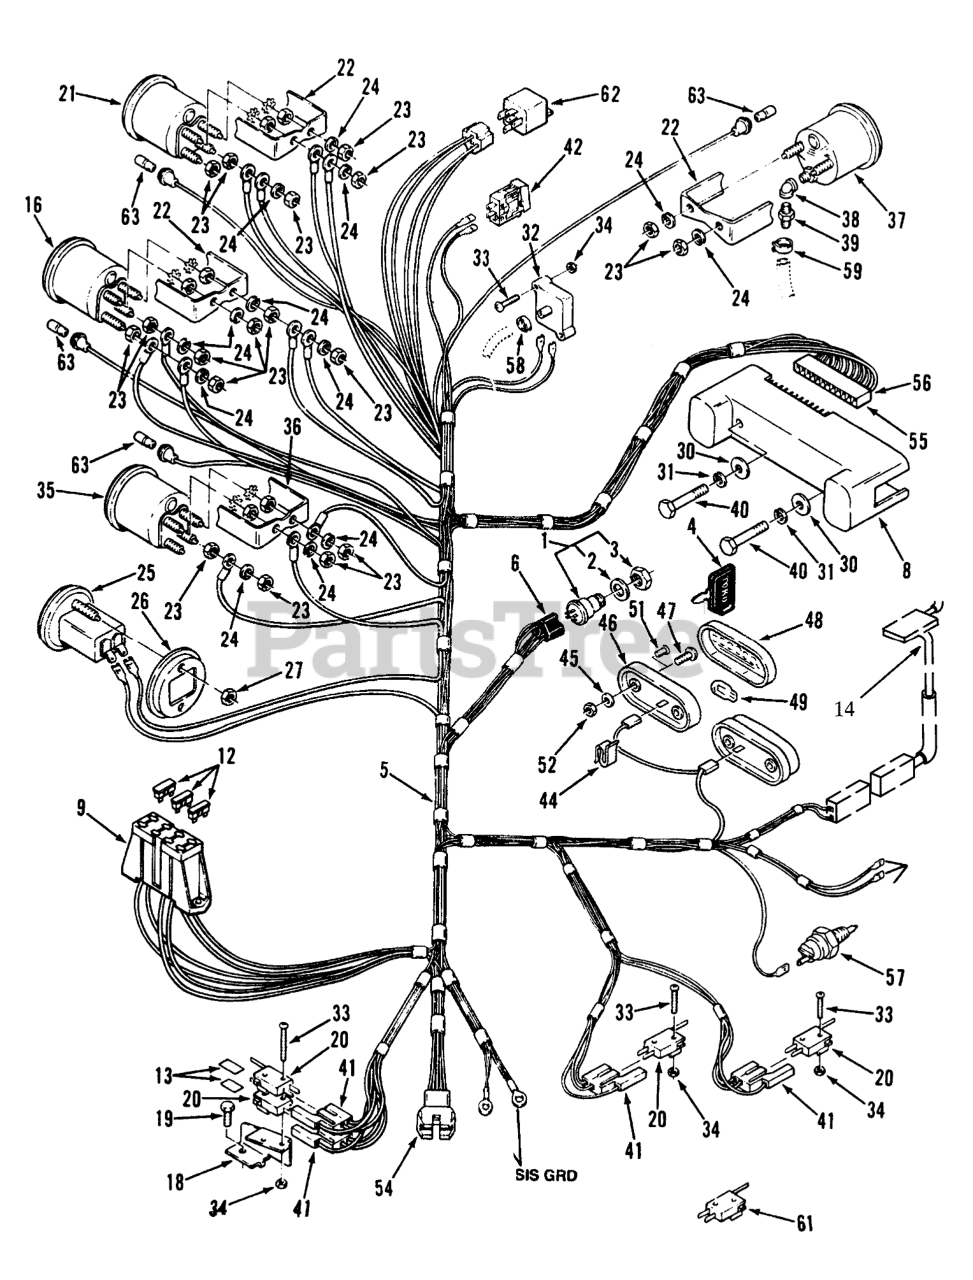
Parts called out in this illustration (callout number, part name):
1	SWITCH-IGNITION
2	Washer
4	KEY-IGNITION
5	WIRING-HARNESS & DIA
6	CONNECTOR-5 WAY-SERV
8	CIRCUIT-BRD 8 LIGHT
9	FUSE-HOLDER 4 WAY
12	FUSE-10 AMP
13	BARRIER - SWITCH
14	SWITCH-SEAT
16	Gauge-Fuel (Includes Item 22
18	Support-Switch
19	Bolt
20	SWITCH
21	Voltmeter (Includes Item 22)
22	CLAMP-MOUNTING
23	Nut
24	Lockwasher
25	Hourmeter (Includes Item 26)
26	Bracket-Mountin
27	Nut
30	WASHER-FLAT
31	WASHER-LOCK
32	SENSOR-AIR CLEANER
33	Screw
34	NUT HEX 4-40 ELAST
35	Tachometer (Includes Item 36)
36	MOUNTING-BRACKET
37	Gauge-Vacuum (Includes Item 22)
38	ELBOW
39	FITTING STRAIGHT
40	SCREW
41	CONNECTOR BODY
42	Light Switch
44	SPEED CLIP
45	WASHER-LOCK, INT
46	BASE-TAIL LIGHT
47	Screw
48	LENS-TAIL LIGHT
49	LIGHT BULB
51	NUT-HEX
52	NUT-HEX
54	9-CIRCUIT CAP
55	Connector-Male
56	Terminal
57	SENSOR-HYDRO OIL HOT
58	CLAMP-HOSE 5/16"
59	Clamp
61	SWITCH - CLUTCH
62	Relay
63	LAMP-MINIATURE GE 53X
